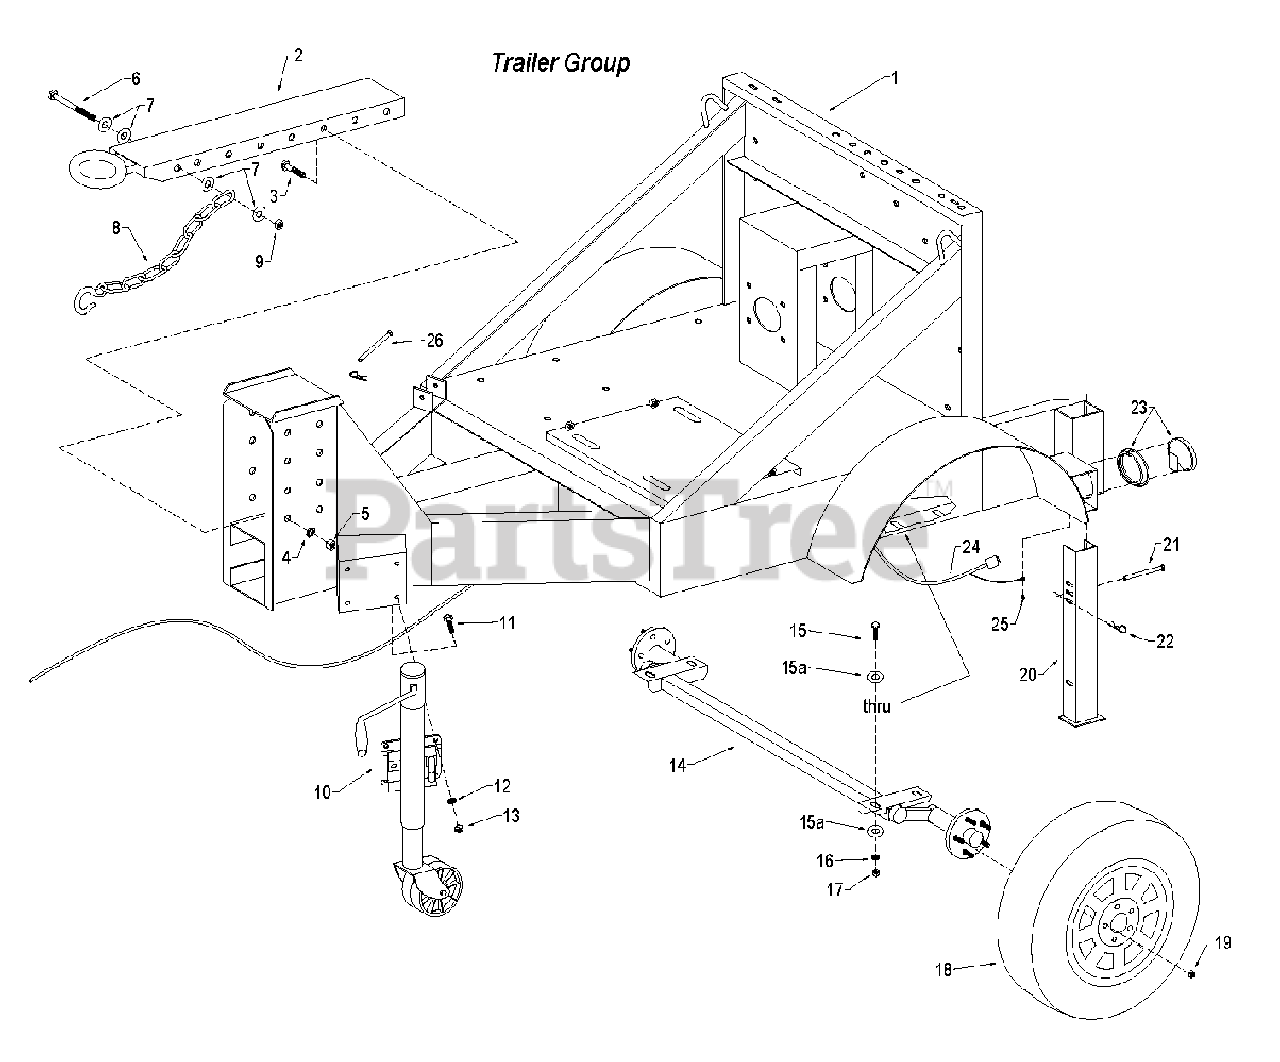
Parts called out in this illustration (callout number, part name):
1	Engine base and trailer frame
3	Bolt, hex - 1/2-13 x 1-1/4"
4	Washer, lock - 1/2
5	Nut, lock - 1/2-13
6	Bolt, hex - 1/2-13 x 7
7	Washer, flat - 1/2
8	Chain, safety towing
9	Nut, lock - 1/2-13
10	Jack, dual wheel support
11	Bolt, hex - 3/8-16 x 1"
12	Washer, lock - 3/8
13	Nut, lock - 3/8-16
14	Axle, Torflex
15	Bolt, hex, black oxide, 1/2-13 x 1-1/4 gr 5
16	Washer, lock - 1/2"
17	Nut, hex end lock – 1/2-13
18	Tire and wheel assy
20	Leg, support
21	Pin, clevis - 3/8 x 4-1/2"
22	Pin, bridge
23	Light, tail/stop assy
24	Harness, wiring
25	Screw, self-tapping - #10 x 1/2 (taillight ground)
26	Pin, clevis - 3/8 x 4-1/2"
